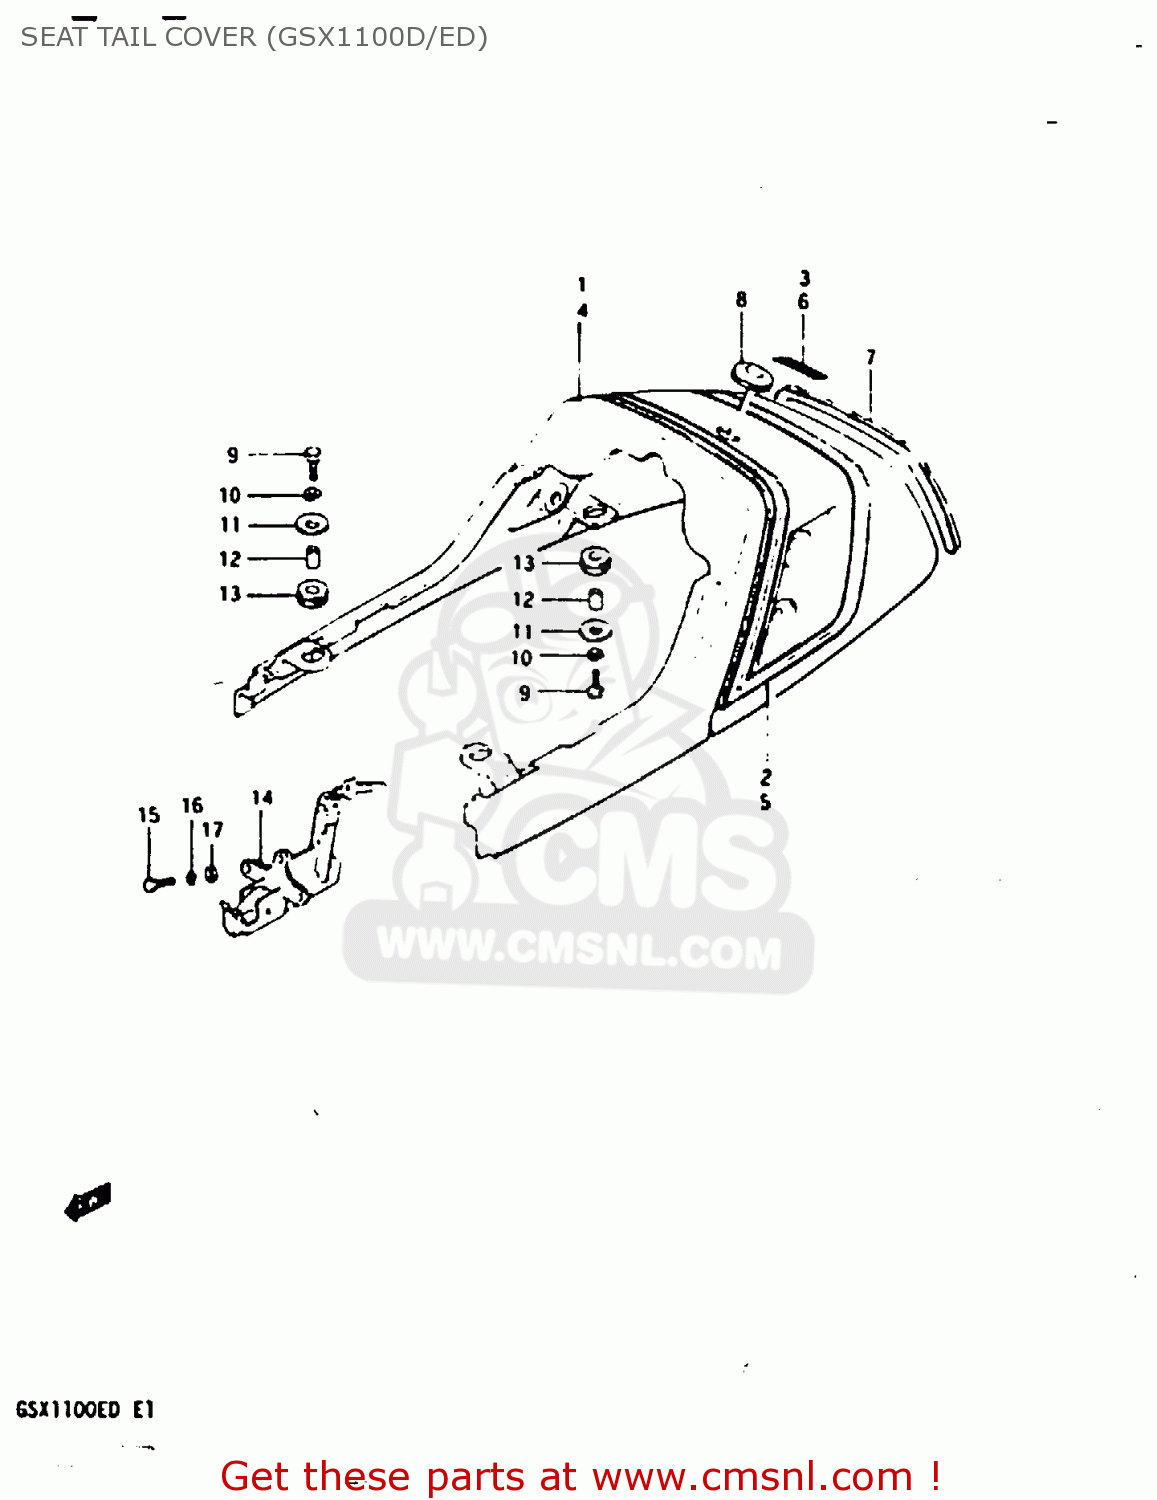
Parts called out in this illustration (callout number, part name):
1	COVER,SEAT TAIL
2	TAPE SET,SEAT TAIL COVER
3	EMBLEM
4	COVER,SEAT TAIL
5	TAPE SET,SEAT TAIL COVER
6	EMBLEM
7	RUBBER,BLIND,SEAT TAIL COVER
8	GROMMET,SEAT LOCK HOLE
9	BOLT
10	LOCK WASHER
11	WASHER(6,5X22X1.6)
12	SPACER(6.5X10.5X12)
13	CUSHION
14	LOCK SET,SEAT
15	BOLT
16	LOCK WASHER
17	WASHER
